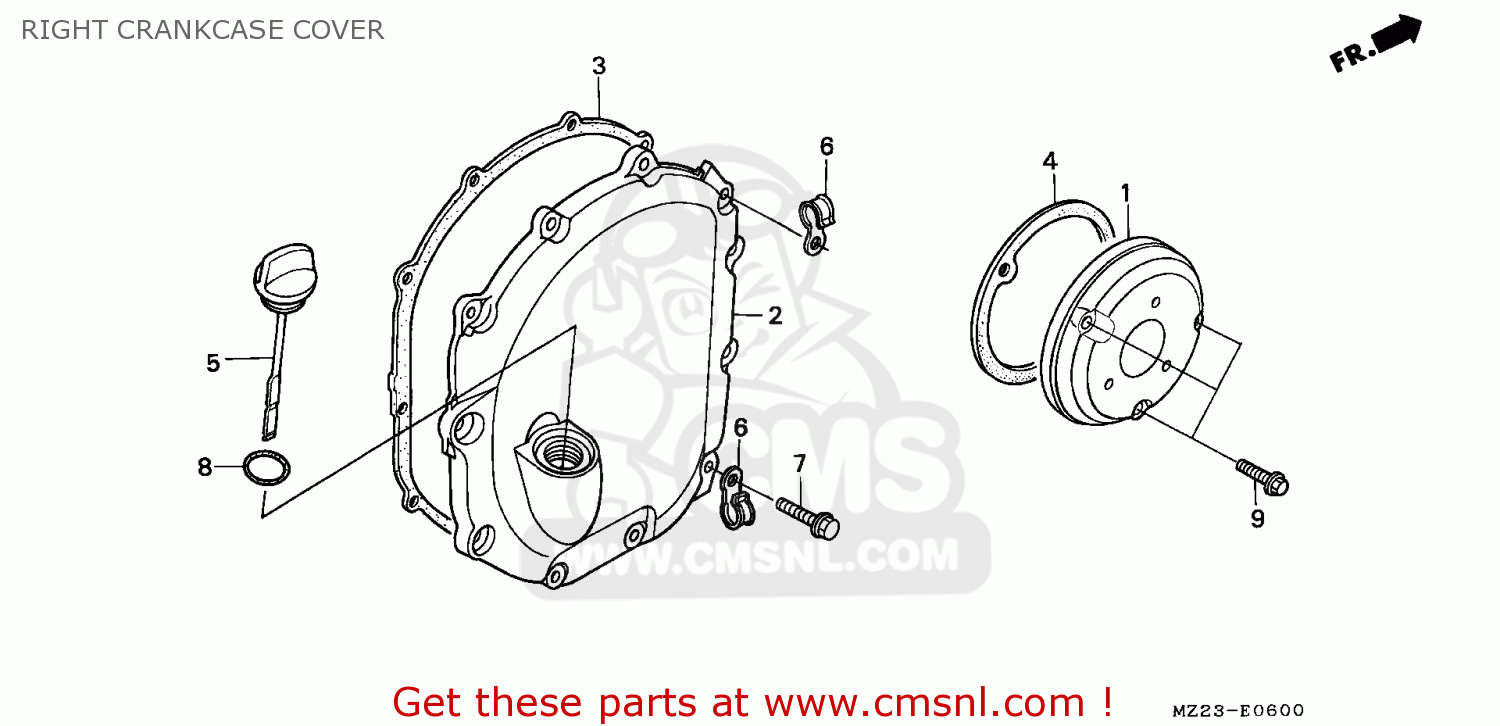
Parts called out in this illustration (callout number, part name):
1	COVER,R CRANK
2	COVER,CLUTCH
3	GASKET,CLUTCH COV (NAS)
4	GASKET,R COVER (NAS)
5	GAUGE,OIL LEVEL
6	CLAMP,CORD
7	BOLT,FLANGE,6X22
8	O RING,21.5M/M
9	BOLT,FLANGE,6X22
